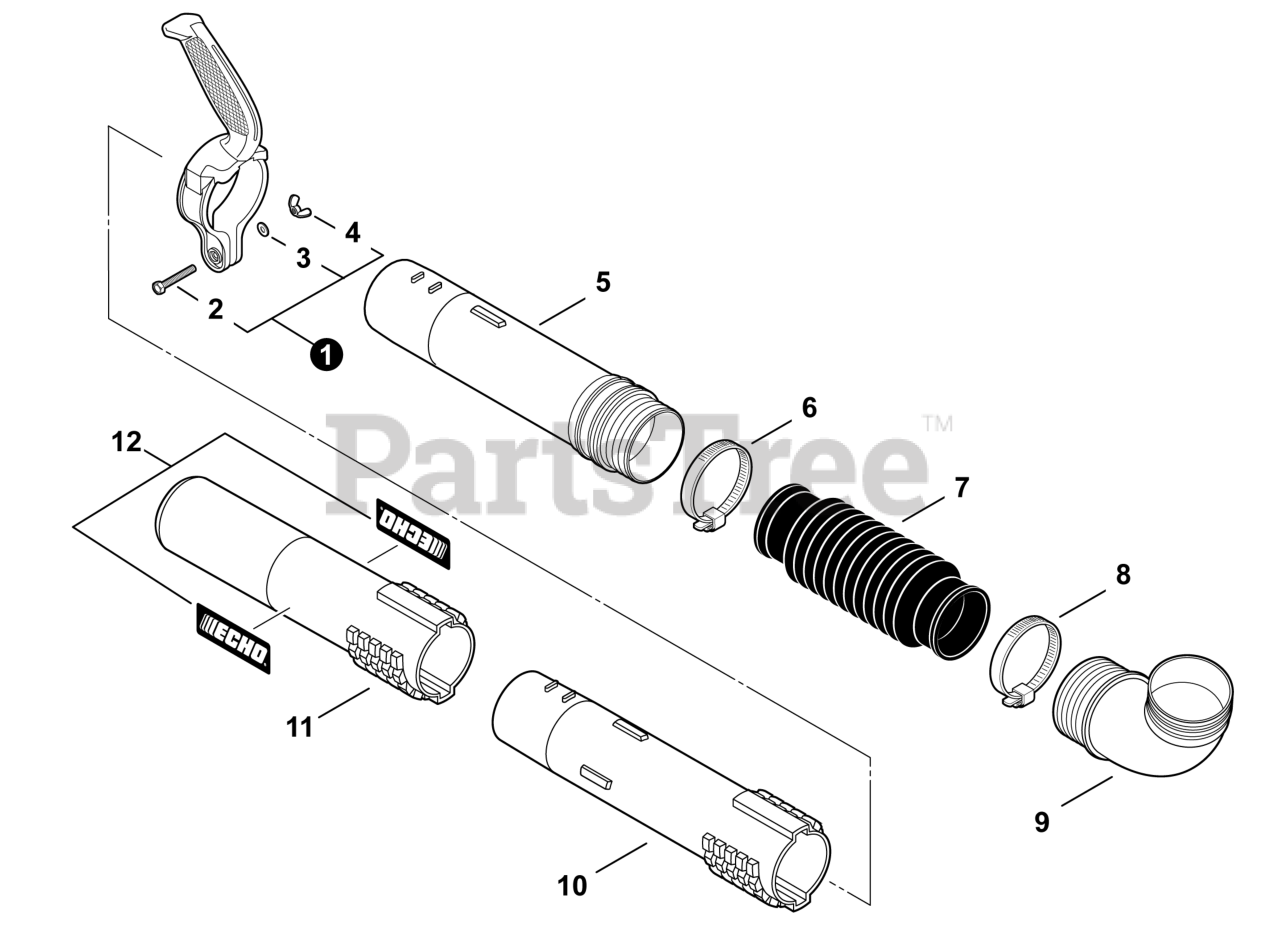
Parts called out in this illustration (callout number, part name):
1	HANDLE ASSY, PB LARGE
2	BOLT 6×45
3	WASHER 6.5×11.5×0.8
4	NUT, WING 6
5	TUBE, BLOWER - SWIVEL
6	CLAMP 58.7 MM / 82.5 MM
7	TUBE, BLOWER - FLEXIBLE
8	CLAMP - BAND
9	TUBE, BLOWER - ELBOW
10	TUBE, BLOWER - STRAIGHT
11	TUBE, BLOWER - NOZZLE
12	LABEL - ECHO
